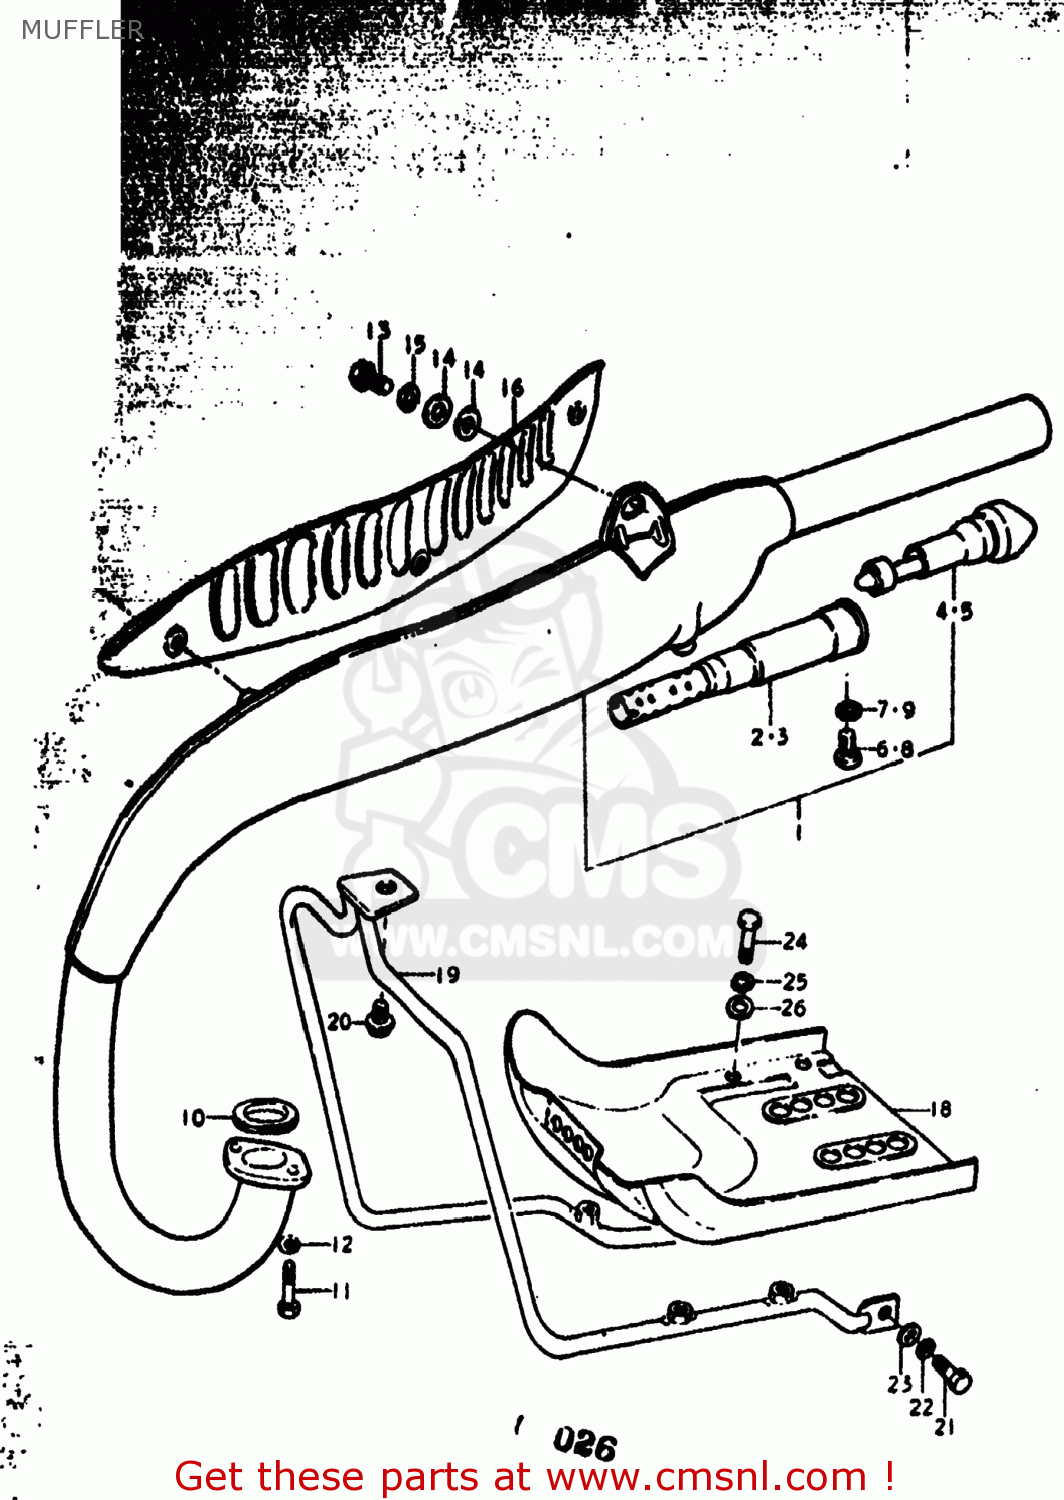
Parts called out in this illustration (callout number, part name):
1	MUFFLER ASSEMBLY
2	ARRESTER,SPARK
3	ARRESTER,SPARK
4	TUBE,MUFFLER CLEAN OUT
5	TUBE,MUFFLER CLEAN OUT
6	SCREW
7	LOCK WASHER
8	SCREW(6X8)
9	LOCK WASHER
10	GASKET,EXHAUST PIPE (NAS)
11	BOLT
12	LOCK WASHER
13	BOLT 10X25
14	WASHER
15	LOCK WASHER
16	COVER,MUFFLER
17	SCREW,6X6
18	PROTECTOR,ENGINE
19	BRACE,SKID PLATE
20	BOLT
21	BOLT
22	LOCK WASHER
23	WASHER
24	BOLT
25	LOCK WASHER
26	WASHER
